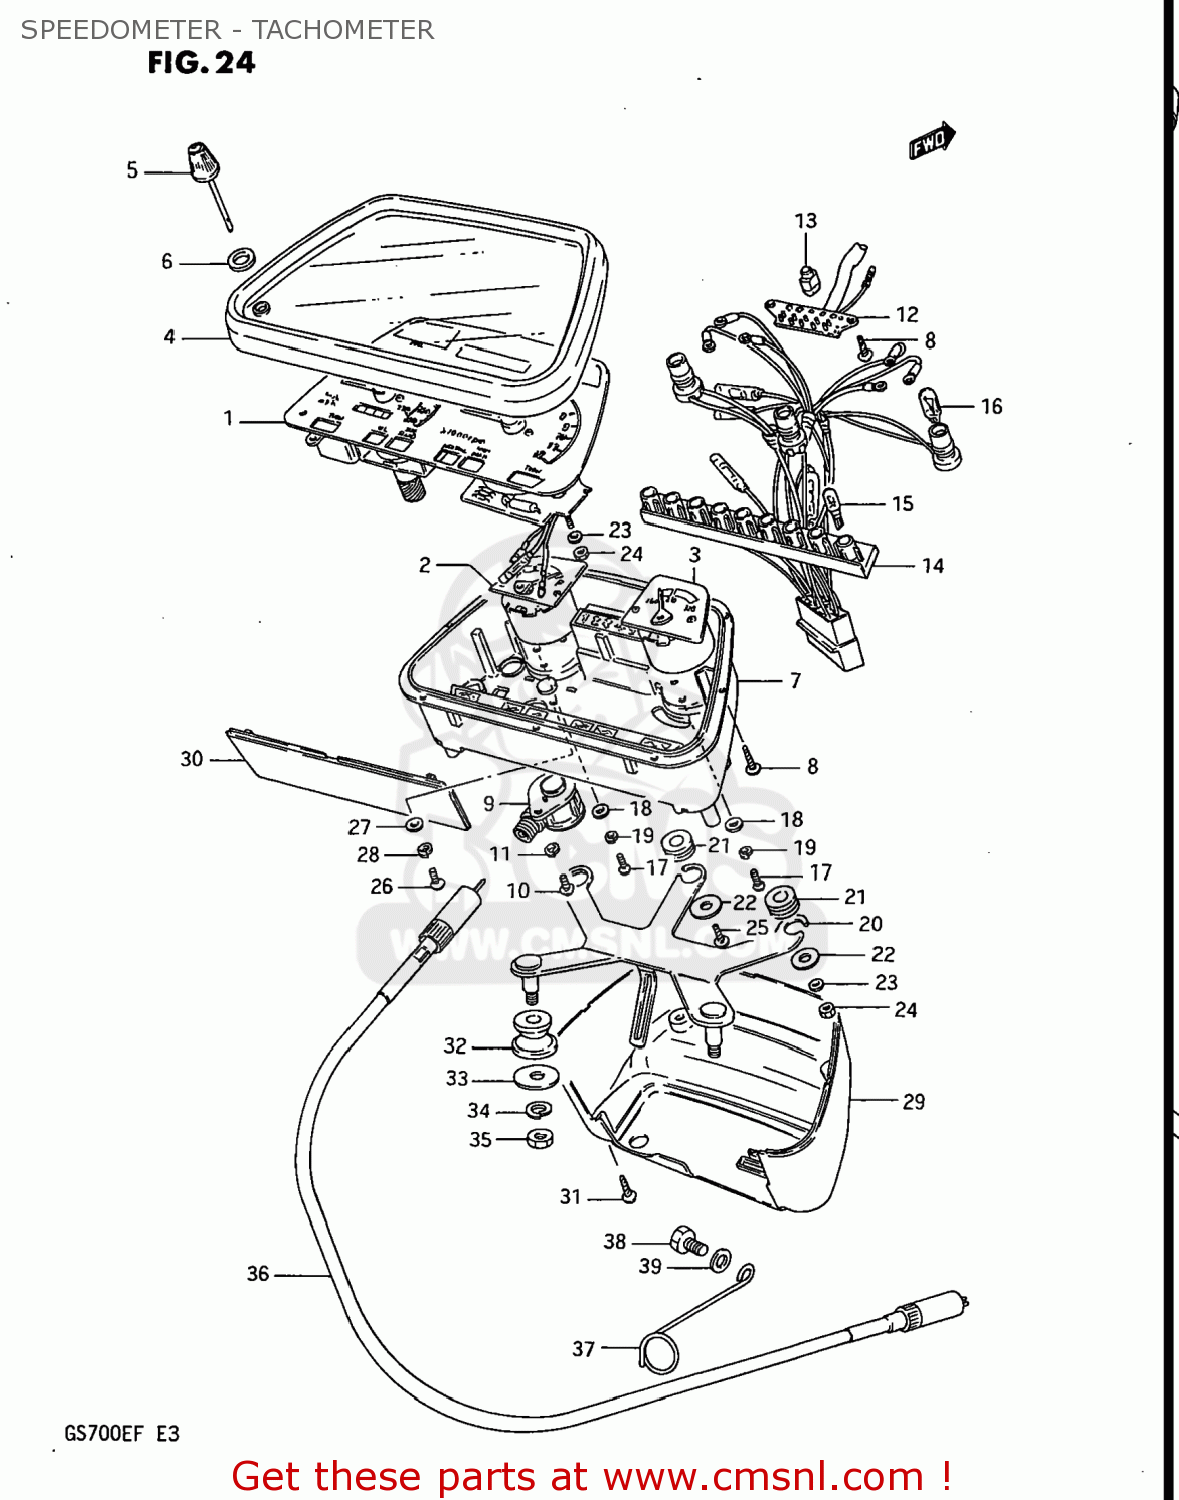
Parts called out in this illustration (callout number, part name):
1	METER,SPEEDOMETER/TACHOMETER (KM/
2	METER,FUEL
3	METER,OIL TEMPERATURE
4	HOOD,METER
5	KNOB,TRIP METER
6	SEAL,TRIP KNOB
7	CASE,METER INNER
8	SCREW
9	GEAR BOX,SPEEDOMETER
10	SCREW 4X10
11	LOCK WASHER
12	SOCKET,GEAR INDICATOR
13	BULB(14V1.12W)
14	SOCKET UNIT,METER
15	BULB(12V3W,WB371,T7)
16	BULB(12V3.4W,T10,BF175-01450A)
17	SCREW 3X12
18	WASHER
19	LOCK WASHER
20	BRACKET,METER
21	CUSHION
22	WASHER,COMBINATION METER
23	LOCK WASHER
24	NUT 4MM
25	SCREW
26	SCREW
27	WASHER
28	LOCK WASHER
29	COVER,METER LWR
30	PLATE,COVER
31	SCREW
32	CUSHION,METER BRACKET
33	WASHER (8.5X20X1.6)
34	WASHER,LOCK,8.
35	NUT
36	CABLE ASSY,SPEEDOMETER
37	CLAMP,SPEEDOMETER CABLE
38	BOLT, UPPER
39	WASHER
